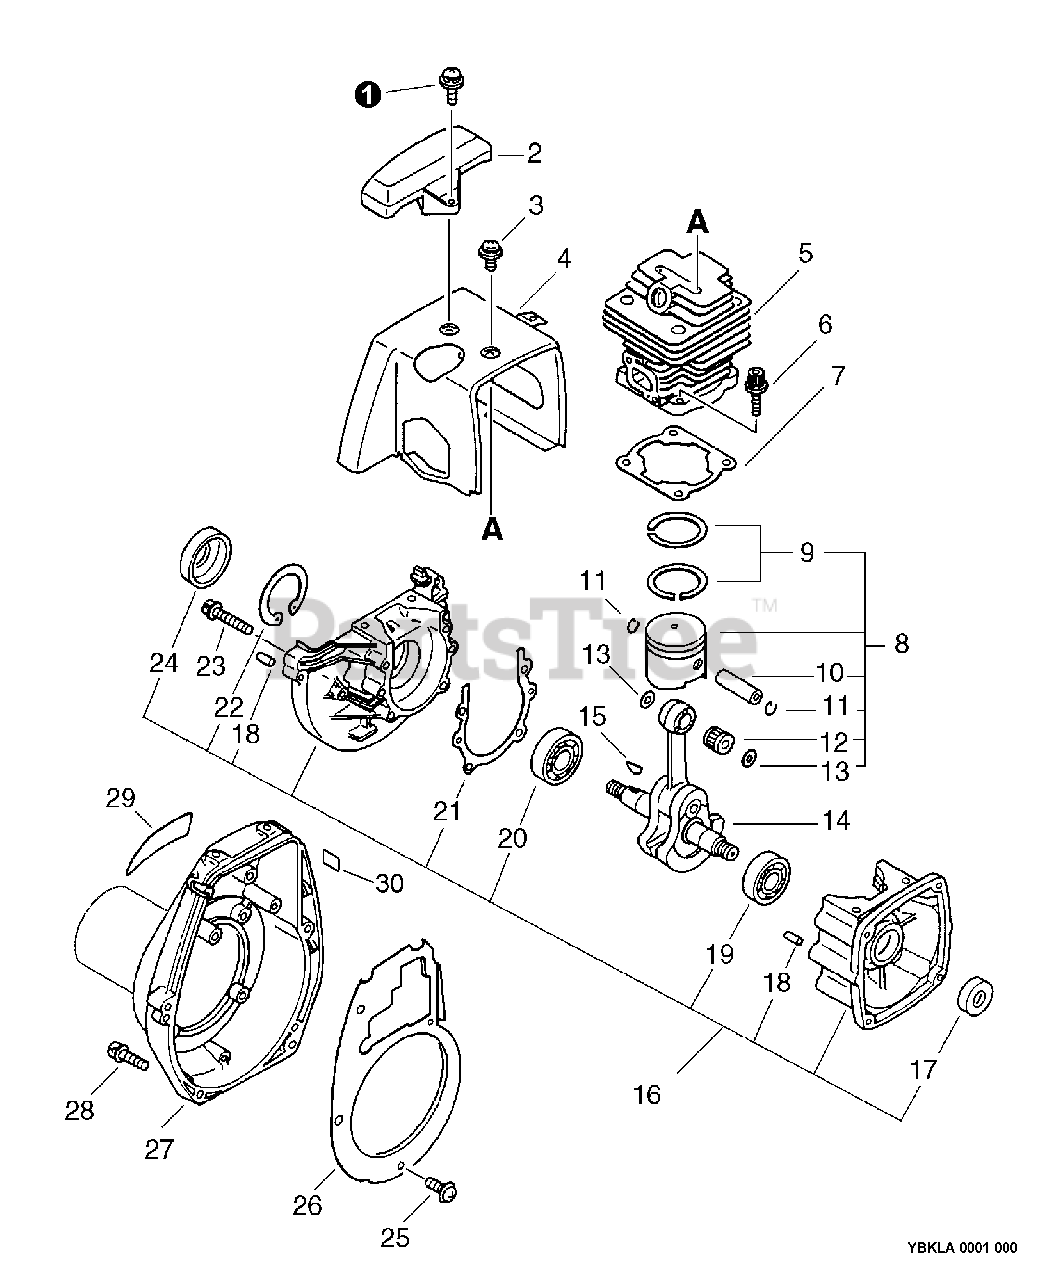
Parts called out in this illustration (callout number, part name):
1	SCREW - 5X14
2	GUARD - TOP
3	SCREW - 5X10
4	COVER, ENGINE
5	CYLINDER
6	SCREW - 5X20
7	GASKET, CYLINDER
8	PISTON KIT
9	RING, PISTON
10	PIN, PISTON
11	RING, RETAINING - 8
12	BEARING, NEEDLE
13	WASHER - 10
14	CRANKSHAFT ASSY
16	CRANKCASE KIT
17	SEAL, OIL - 12
18	PIN - LOCATING
19	BEARING, BALL - 6201
20	BEARING, BALL - 6202
21	GASKET, CRANKCASE
22	RING, RETAINING - 35
23	SCREW - 5X30
24	SEAL, OIL
25	SCREW - 4X10
26	SHIELD, FAN
27	CASE, FAN
28	SCREW - 5X25
29	LABEL - MODEL SRM-4605U
30	LABEL - HOT SURFACE
